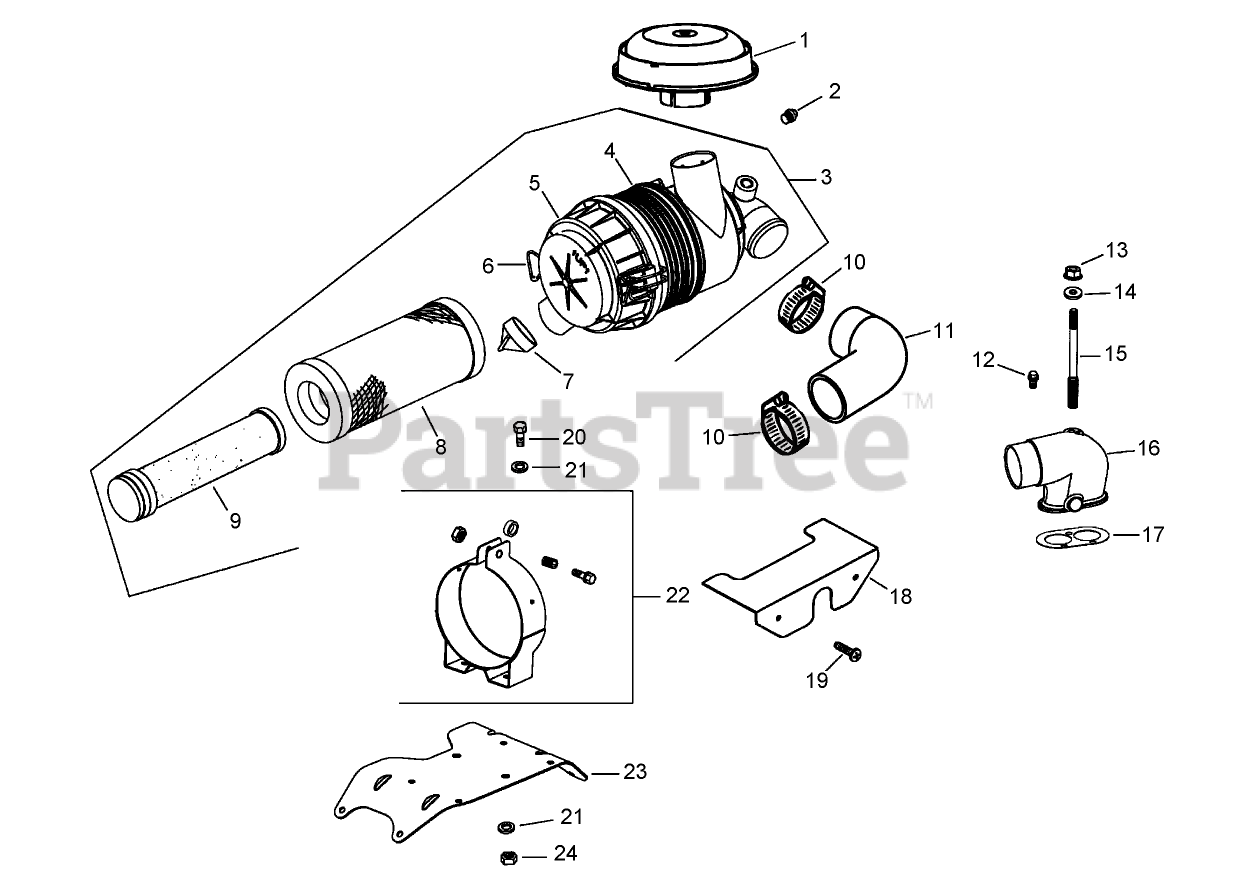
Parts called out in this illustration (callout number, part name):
1	Hood-Cleaner, Air
2	Plug-Pipe
3	Air Cleaner ASM (Includes 4-9)
4	Housing-Air Cleaner, Heavy Duty
5	Cover ASM (Includes 6, 7)
6	Clip
7	Valve-Ejector, Dust
8	Element-Air Filter, Primary
9	Element-Air Filter, Safety
10	Clamp-Hose
11	Hose-Cleaner, Air
12	Screw-HSH
13	NUT-FLANGE (M6X1.0)
14	Washer-Copper
15	STUD-CARBURETOR (M6X1.0X122)
16	Adapter-Air Cleaner, Remote
17	Gasket-Base, Air Cleaner
18	Shield-Debris
19	SCREW-PPH (11-16X3/4)
20	Screw-HF (M6x1.0x16)
21	Washer-Flat (1/4)
22	Air Cleaner Bracket ASM
23	Bracket-Cleaner, Air
24	Nut-Lock (M6X1.0)
